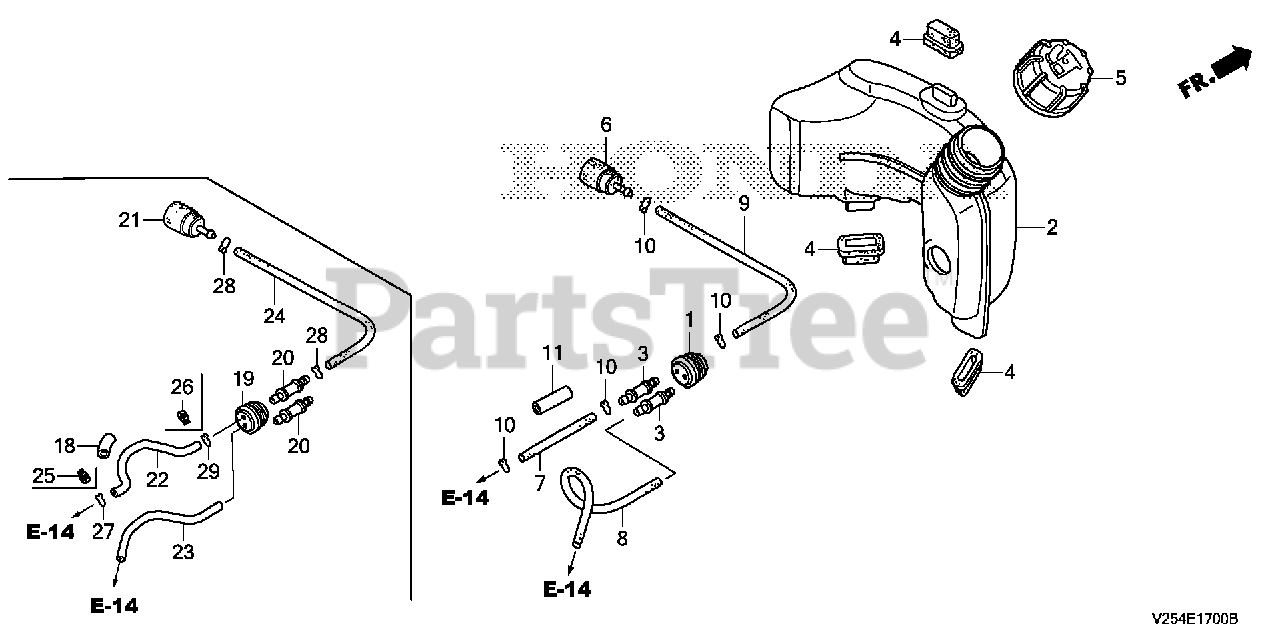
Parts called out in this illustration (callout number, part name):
1	GROMMET, FUEL TUBE
2	TANK, FUEL
4	RUBBER, TANK MOUNTING
5	CAP ASSY., FUEL TANK
6	FILTER, FUEL
7	TUBE, FUEL TANK
8	TUBE, FUEL RETURN
9	TUBE A, FUEL
10	CLIP, TUBE
